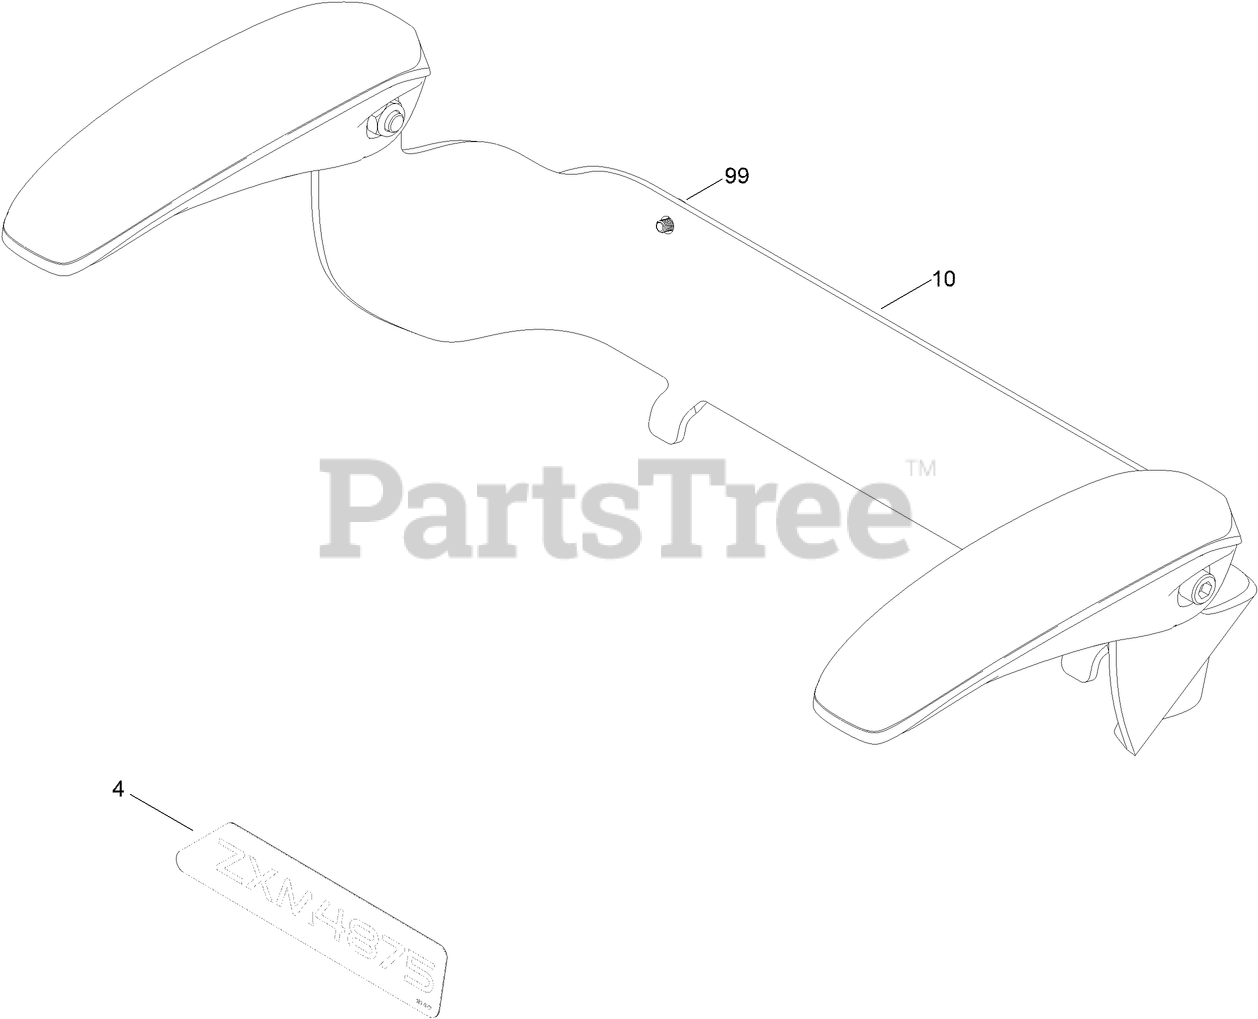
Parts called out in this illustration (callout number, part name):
4	DECAL ZXM4875
10	KIT-ARM REST
99	SCREW-HH
